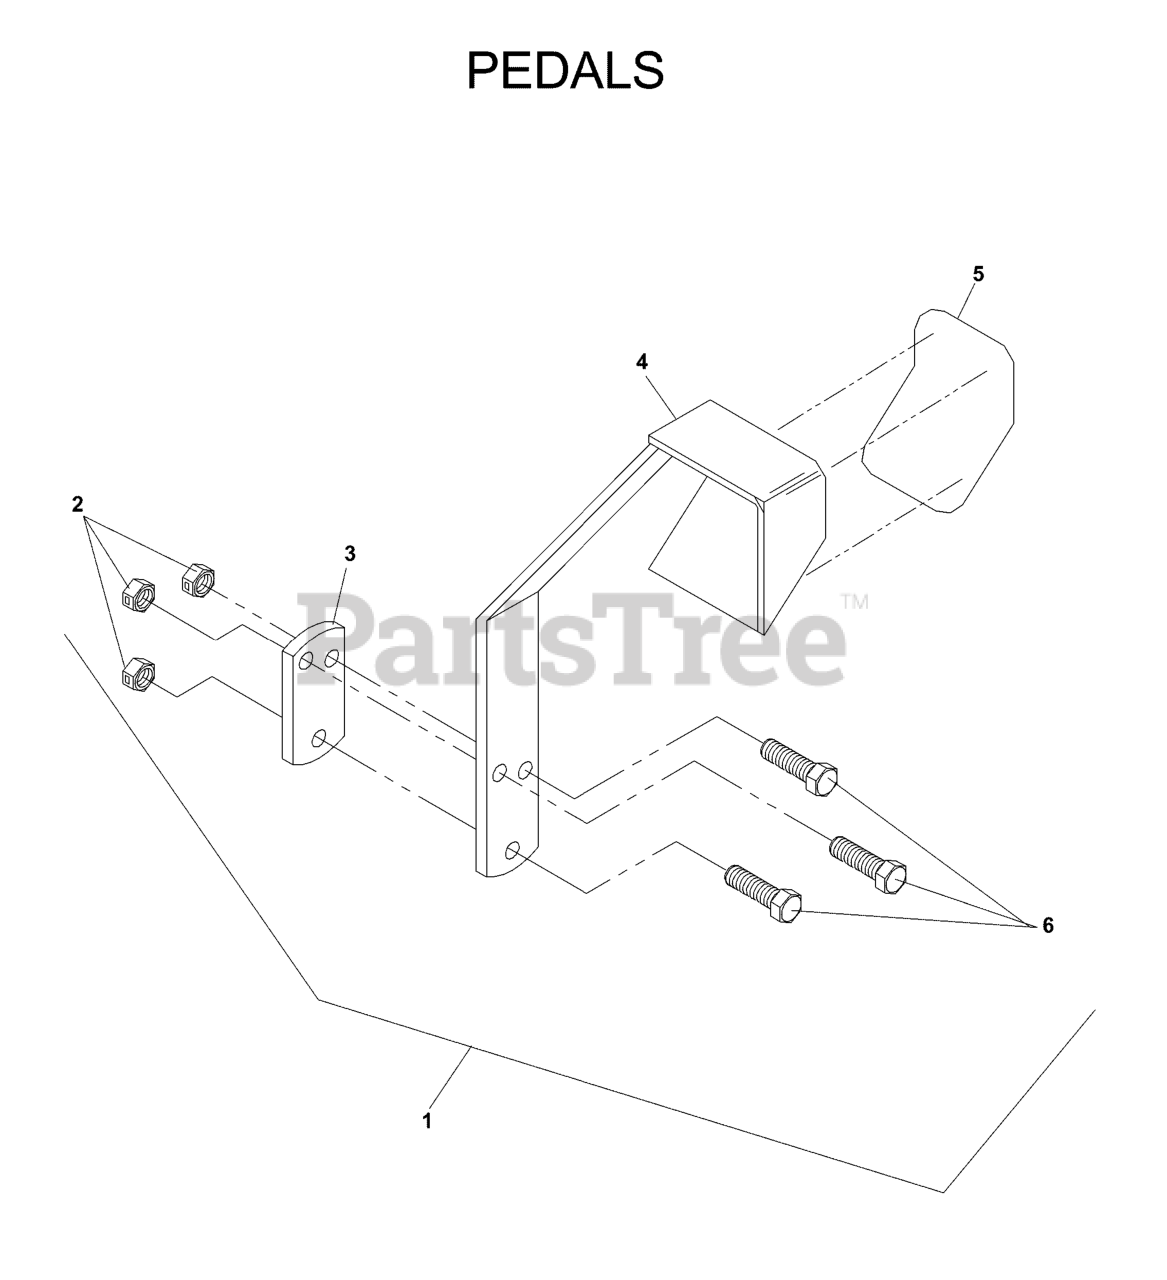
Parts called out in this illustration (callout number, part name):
1	FOOT ASSIST DECK LIFT-GEN II
2	NUT 3/8-16 NYLOC
3	TIGHTENING PLATE BLK
4	LIFT PEDAL BLK
5	ANTI-SKID PAD
6	HCS 3/8C X 1 1/2
